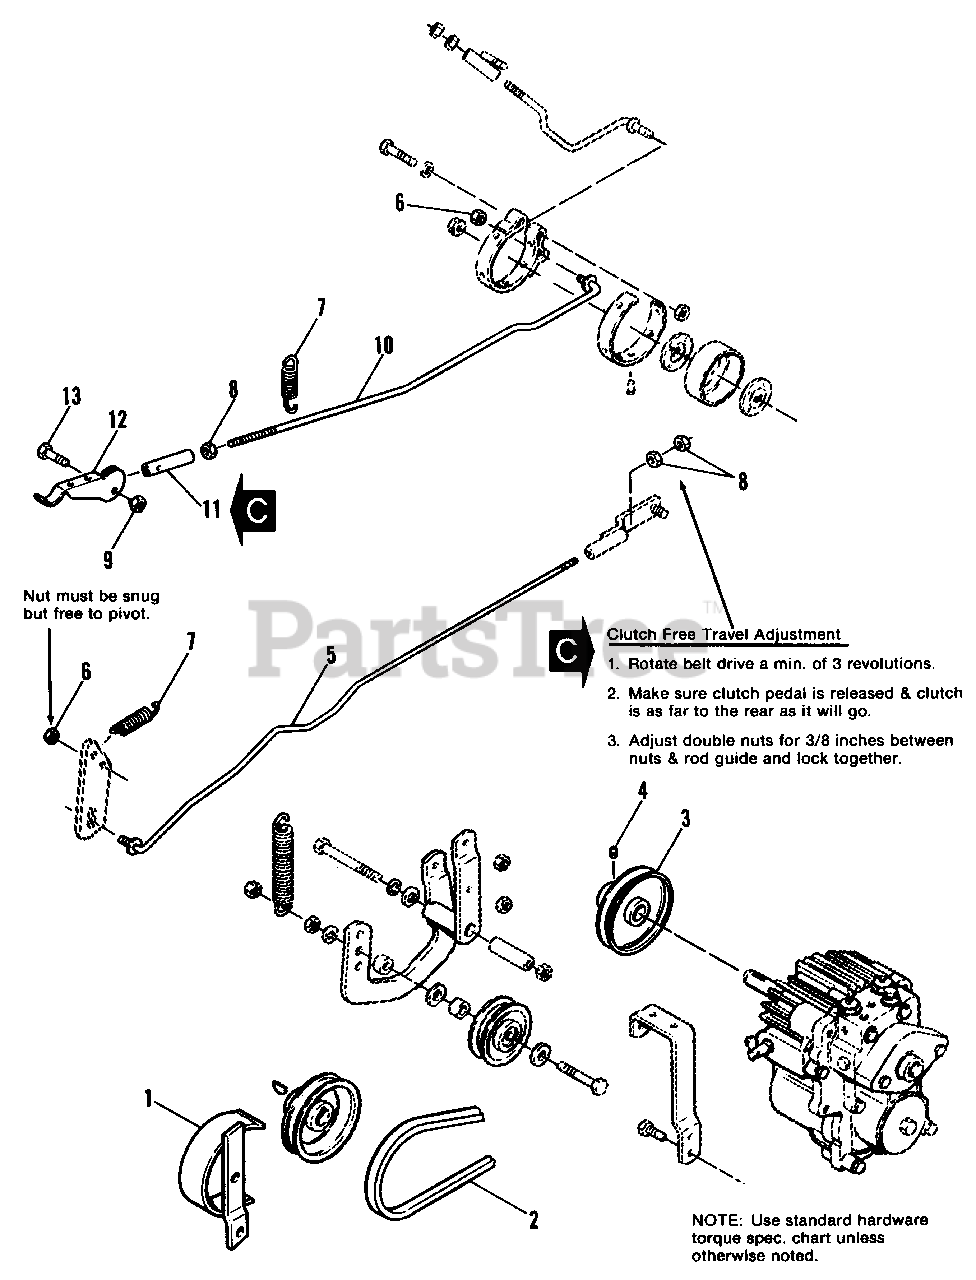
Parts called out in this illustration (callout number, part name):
1	GUARD ASSY.
2	"V" BELT, Hydro Pump
3	PULLEY
4	SETSCREW, Sq. Hd., 5/16-18 x 3/8
5	ROD, Clutch
6	LOCKNUT, Hex, 5/16-18
8	NUT, Hex, Full, 5/16-18
9	LOCKNUT, Hex, 1/4-20
10	ROD ASSY.
12	LEVER, Parking Brake
13	CAPSCREW, Hex Hd., 1/4-20 x 1-1/4
